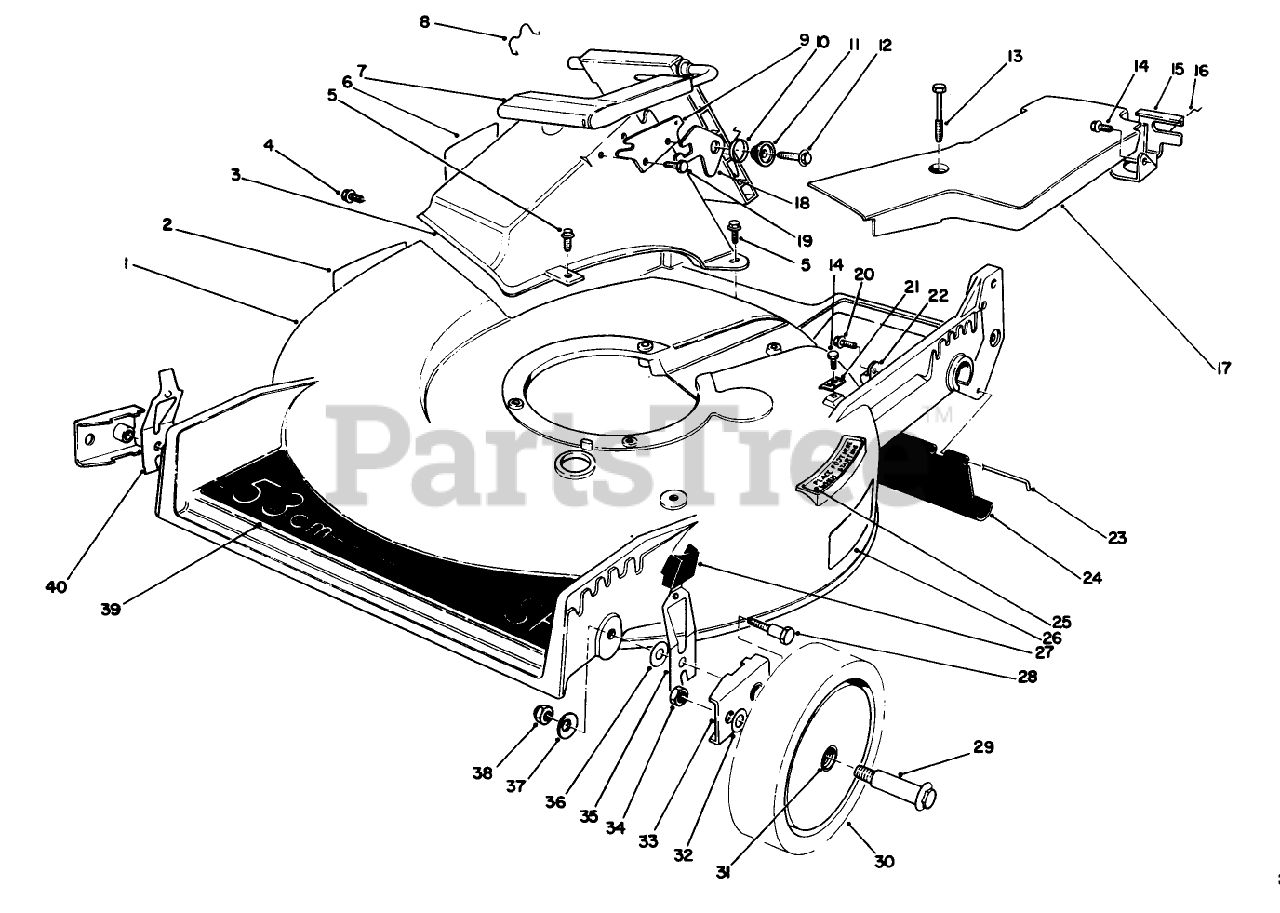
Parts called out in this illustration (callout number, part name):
2	DECAL-DANGER
4	SCREW AND WASHER ASM
5	SCREW-HWH
8	DOOR RET SPRING
9	DOOR LATCH PLATE
10	TORSION SPRING
11	DOOR SPACER
12	SCREW-HWH
13	SCREW-HWH
14	SCREW-HWHTF
16	RETAINER-CABLE
18	SAFETY LATCH
19	SCREW-PLASTITE
20	SCREW
21	CLAMP-CABLE
22	CLAMP-CABLE
23	ROD-SHIELD
25	DECAL - STEP PAD INT'L
27	KNOB-ARM
28	PIVOT SCREW
29	BOLT-WHEEL
31	BUSHING
32	WASHER
33	HP PIVOT ARM ASM
36	WASHER-PIVOT
37	WASHER-BELLEVILLE
38	NUT-LOCK, NI
